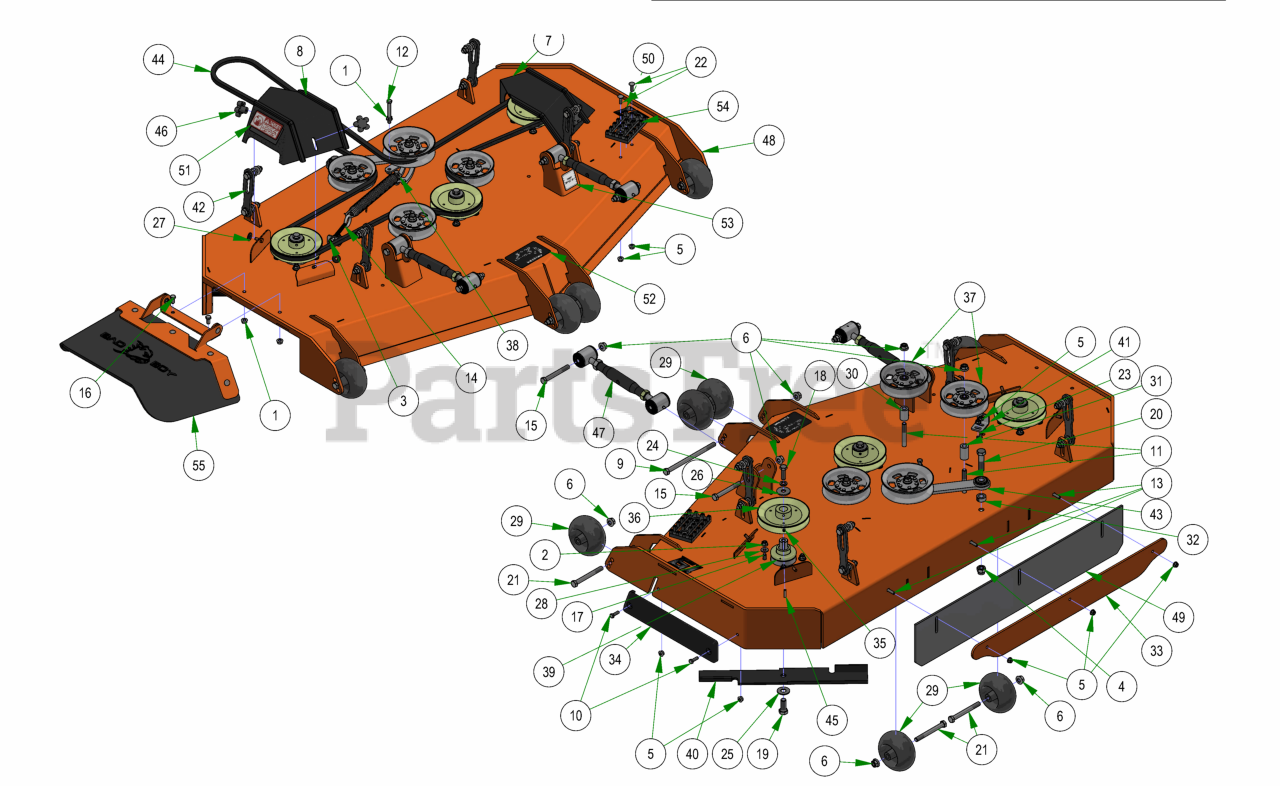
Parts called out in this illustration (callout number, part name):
1	3/8-16 HEX SERRATED FLANGE NUT HARD/ZINC
2	3/8-16 NYLON INSERT FLANGE LOCKNUT (GR.F) ZINC
3	3/8-16 HEX NUT ZINC
4	5/8-11 NYLON INSERT LOCKNUT ZINC
5	5/16-18 NYLON INSERT FLANGE LOCKNUT ZINC
6	1/2-13 NYLON INSERT FLANGE LOCKNUT ZINC
7	2019 61" Outlaw Gen2 Pulley Cover Left
8	2019 61" Outlaw Gen2 Pulley Cover Right
9	1/2-13 X 8 HEX CAP SCREW GR 5 ZINC
10	5/16-18 X 1 HEX CAP SCREW (GR.5) ZINC
11	1/2-13 X 3-1/2 HEX FLANGE BOLT (GR.8) ZINC
12	3/8-16 X 3 HEX CAP SCREW (GR.5) ZINC
13	5/16-18 X 1-1/4 CARRIAGE BOLT ZINC
14	4" 3/8-16 Eye Bolt
15	1/2-13 X 4 HEX CAP SCREW (GR.8) ZINC YELLOW
16	3/8-16 X 3/4 HEX CAP SCREW (GR.5) ZINC
17	3/8-16 X 1-1/2 HEX CAP SCREW (GR.5) ZINC
18	1/2-20 X 1-1/2 HEX CAP SCREW (GR.5) ZINC
19	5/8-18 X 1-1/2 HEX CAP SCREW (GR.8) ZINC YELLOW
20	5/8-11 X 2-1/2 HEX CAP SCREW (GR.5) ZINC
21	1/2-13 X 4-1/2 HEX CAP SCREW (GR.5) ZINC
22	5/16-18 X 1 CARRIAGE BOLT (GR.8) ZINC
23	5/16-18 X 7/8 CARRIAGE BOLT ZINC
24	1/2 SPLIT LOCKWASHER (GR.8) ZINC/YELLOW
25	5/8 USS FLAT WASHER (1-3/4" OD) GR.8 ZINC YELLOW
26	1/2 BELLEVILLE WASHER (1-5/8 OD X .140 THK) ZINC
27	.360 ID X .983 OD X .120 THICK FLAT WASHER NYLON BLACK
28	5/16 USS FLAT WASHER (7/8 OD) ZINC
29	2019 Deck Wheel
30	.502 ID X .750 OD X 1.500 Long Spacer
31	1 3/4" Pulley Spacer
32	5/8 SOLID SHAFT COLLAR (W/1 SET SCREW) ZINC
33	61 Bolt in Baffle Deck v2 Stripping Plate
34	REVISED TRIM BUMPER_20180226
35	5/16-24 X 1/4 SOCKET SET SCREW (CUP PT) PLAIN
36	6 1/4" Drive Pulley
37	5-3/4 Idler Pulley
38	2019 Outlaw Gen2 Deck Spring
39	OUTLAW SPINDLE ASSEMBLY
40	61 inch Fusion Blade
41	2019 Deck Eye Bolt Tab
42	Deck Hanger Assembly
43	2019 Renegade Deck Idler
44	Deck Belt for 61" Renegade
45	1/4 X 1 SQ MACHINERY KEY 1018 STL PLN
46	5/16" Knob
47	Turnbuckle Assembly (M20-2.5)
48	2019 Sloped 61" Deck
49	R Series Rubber For Deck
50	61" Deck Decal
51	Danger Decal-Spindle/Discharge
52	2019 Renegade Deck Belt Route Decal
53	Deck Impact Patent Decal 9591803
54	Deck Step Assembly
55	2019 Outlaw Gen2 Chute Assembly
